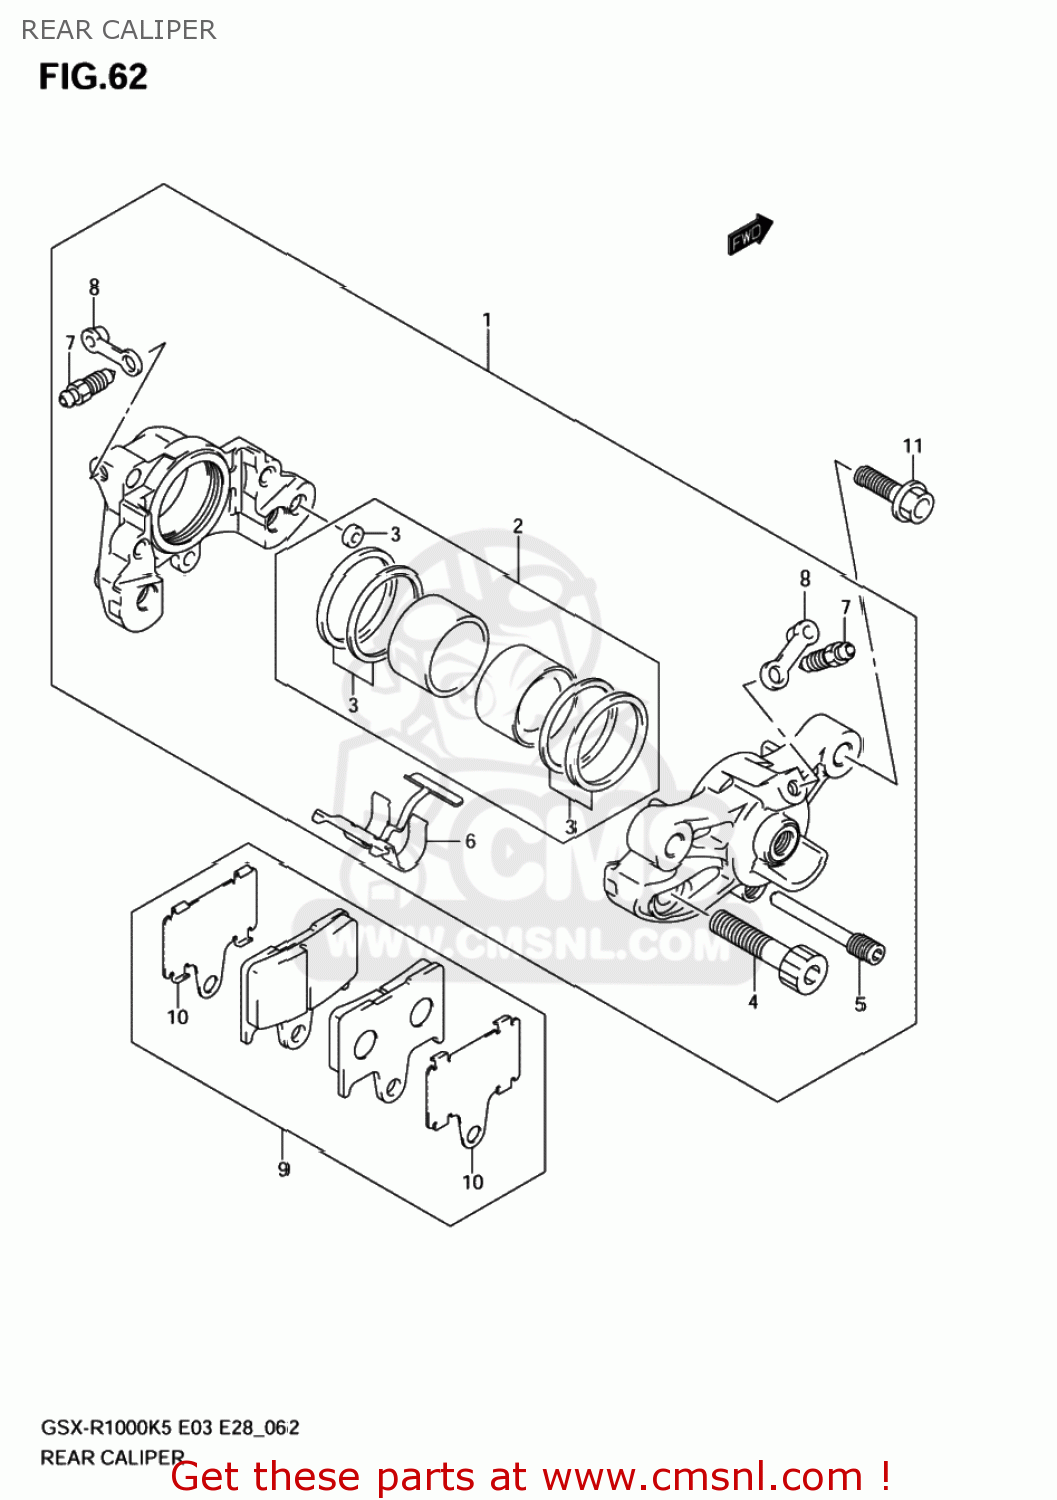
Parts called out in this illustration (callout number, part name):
1	CALIPER ASSY,RR
2	PISTON SET
3	SEAL SET,PISTON
4	BOLT,HOUSING
5	PIN,PAD
6	SPRING,PAD
7	BLEEDER
8	CAP,BLEEDER
9	PAD & SHIM SET (NAS)
10	SHIM,PAD
11	BOLT(8X28)
